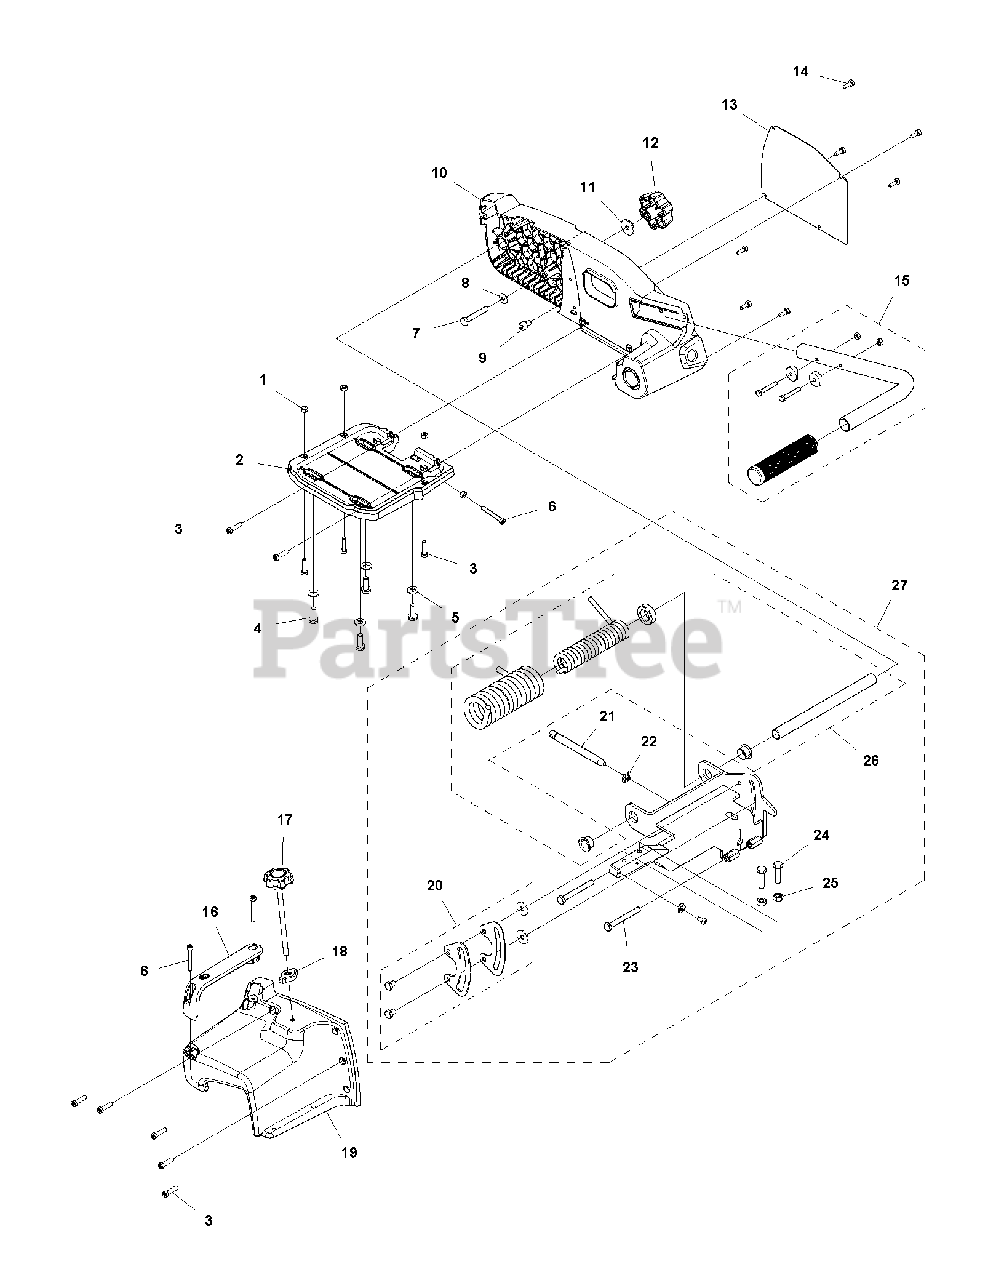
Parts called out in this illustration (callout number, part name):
1	HEXAGON LOCKING NUT2 are included in kit 15
3	SCREW IHSCM
5	WASHER
25	HEXAGON NUT
